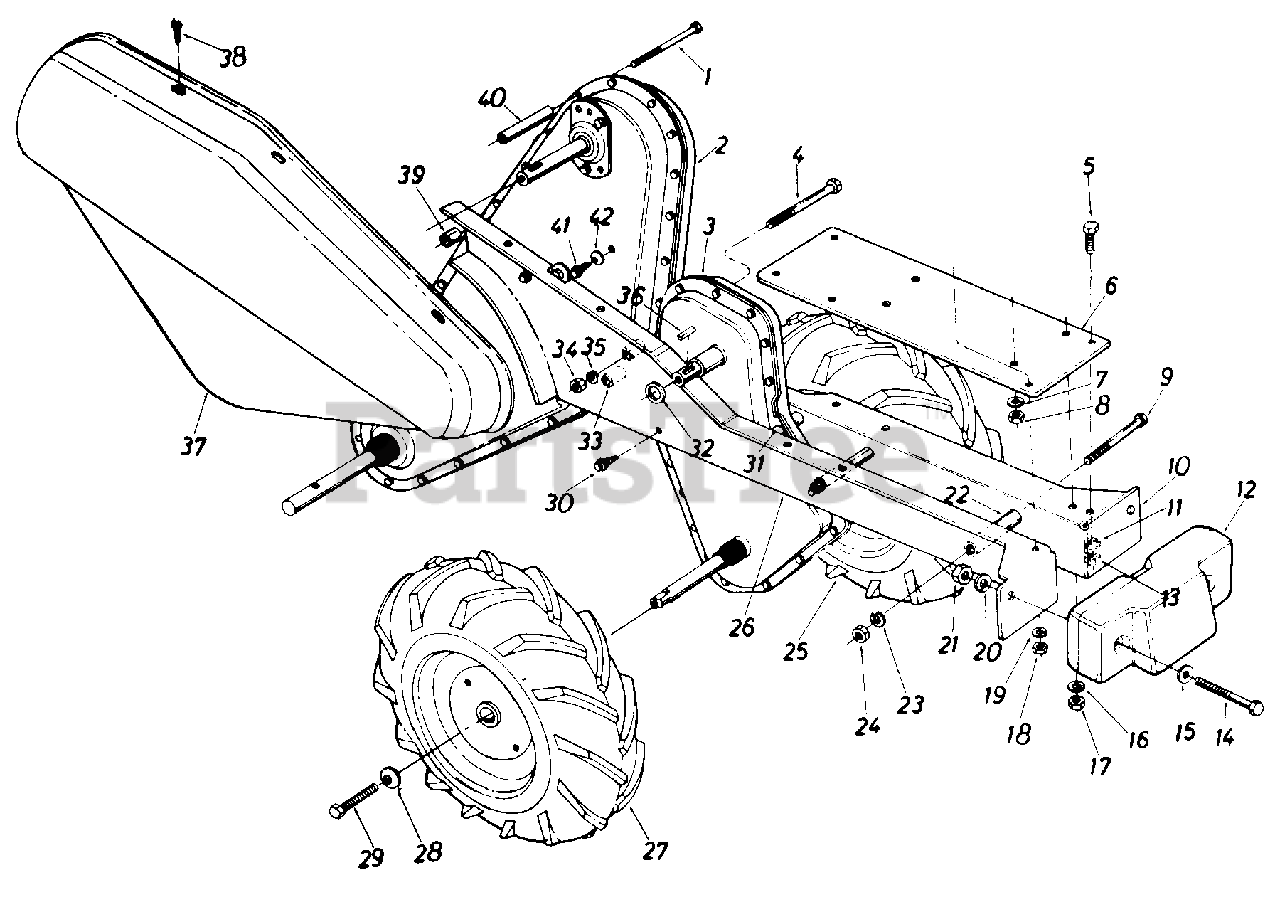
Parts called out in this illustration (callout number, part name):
1	Hex Bolt 5/16-18 x 3.00" Lg.*
2	Chain Case Ass'y. Comp. Tines
3	Chain Case Ass'y. Comp. Wheels
4	Hex Bolt 5/16-18 x 3.00" Lg.
5	Hex Bolt 5/16-18 x .75" Lg.
8	Hex Nut 5/16-18 Thd.
9	Hex Bolt 3/8-24 x 3.00" Lg.
12	Weight 35#
13	Hex Nut 5/16-18 Thd.
14	Hex Bolt 1/2-13 x 4.00" Lg.
15	Fl-Wash. .510" I.D. x 1.0" O.D.
16	L-Wash. 5/16" I.D.
17	Hex Nut 5/16-18 Thd.
18	Hex Nut 5/16-18 Thd.
19	L-Wash. 5/16" I.D.
20	L-Wash. 1/2" I.D.
21	Hex Nut 1/2-13 Thd.
22	Spacer.38" I.D. x .62" O.D. x 2.18" Lg.
23	L-Wash. 3/8" I.D.
24	Hex Nut 3/8-24 Thd.
25	Wheel Ass'y. Comp. 12.5 x 3.5 L.H.
28	Belleville Wash. .345" I.D. x .88" O.D.
29	Hex Bolt 5/16-24 x .62" Lg.
30	Hex Wash. Hd. SF-Tap Scr. 5/16-24 x .50" Lg.
31	Spacer.326" I.D. x .47" O.D. x .96" Lg.
32	Fl-Wash. .635" I.D. x 1.00" O.D.
33	Spacer.326" I.D. x .47" O.D. x .96" Lg.
34	Hex Nut 5/16-18 Thd.
35	L-Wash. 5/16" I.D.
36	Sq. Key 3/16 x .75" Lg.
37	Belt Cover
38	Hex Wash. Hd. SF-Tap Scr. 1/4-20 x .50" Lg.
39	Spacer.326" I.D. x .47" O.D. x .96" Lg.
40	Spacer.375" I.D. x .500" O.D. x 2.00" Lg.
41	Hex Wash. Hd. SF-Tap Scr. 1/4-20 x .50" Lg.
42	Bell-Wash. .265" I.D. x .75" O.D.
